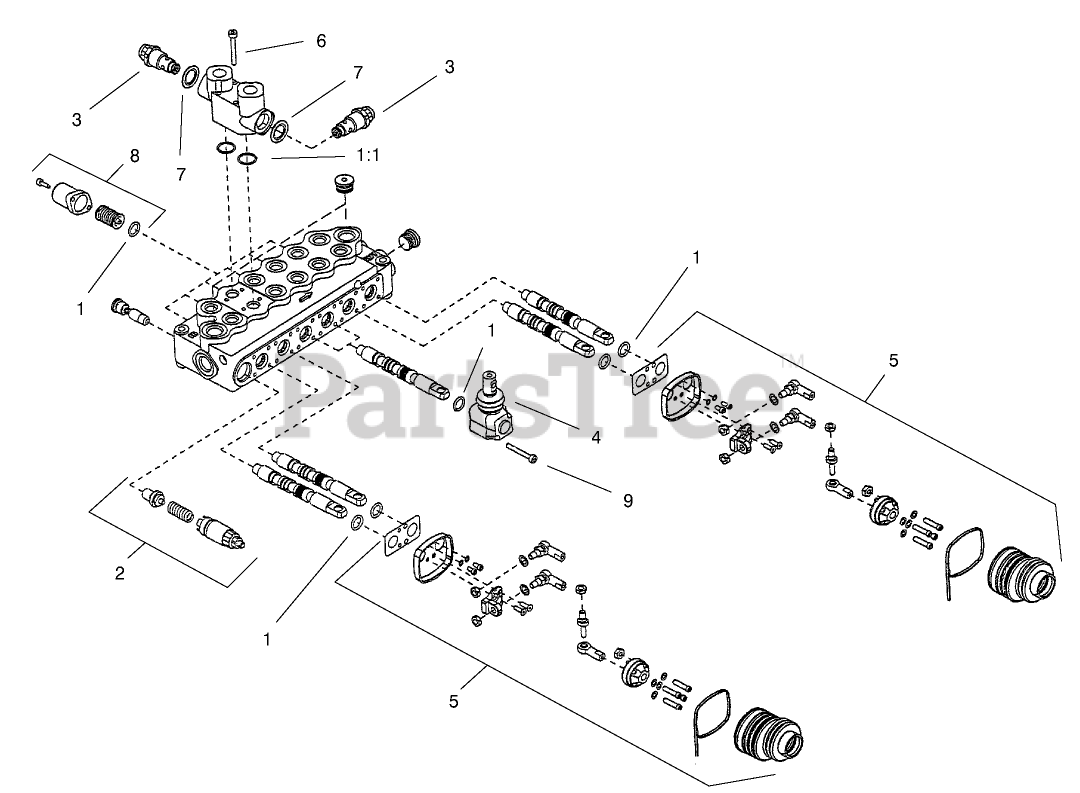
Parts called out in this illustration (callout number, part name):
1	VALVE SEAL KIT
1:1	O-RING
2	RELIEF VALVE KIT
3	CARTRIDGE-RELIEF
4	LEVER KIT
5	JOYSTICK KIT
7	WASHER
8	HIGH FORCE SPRING KIT
